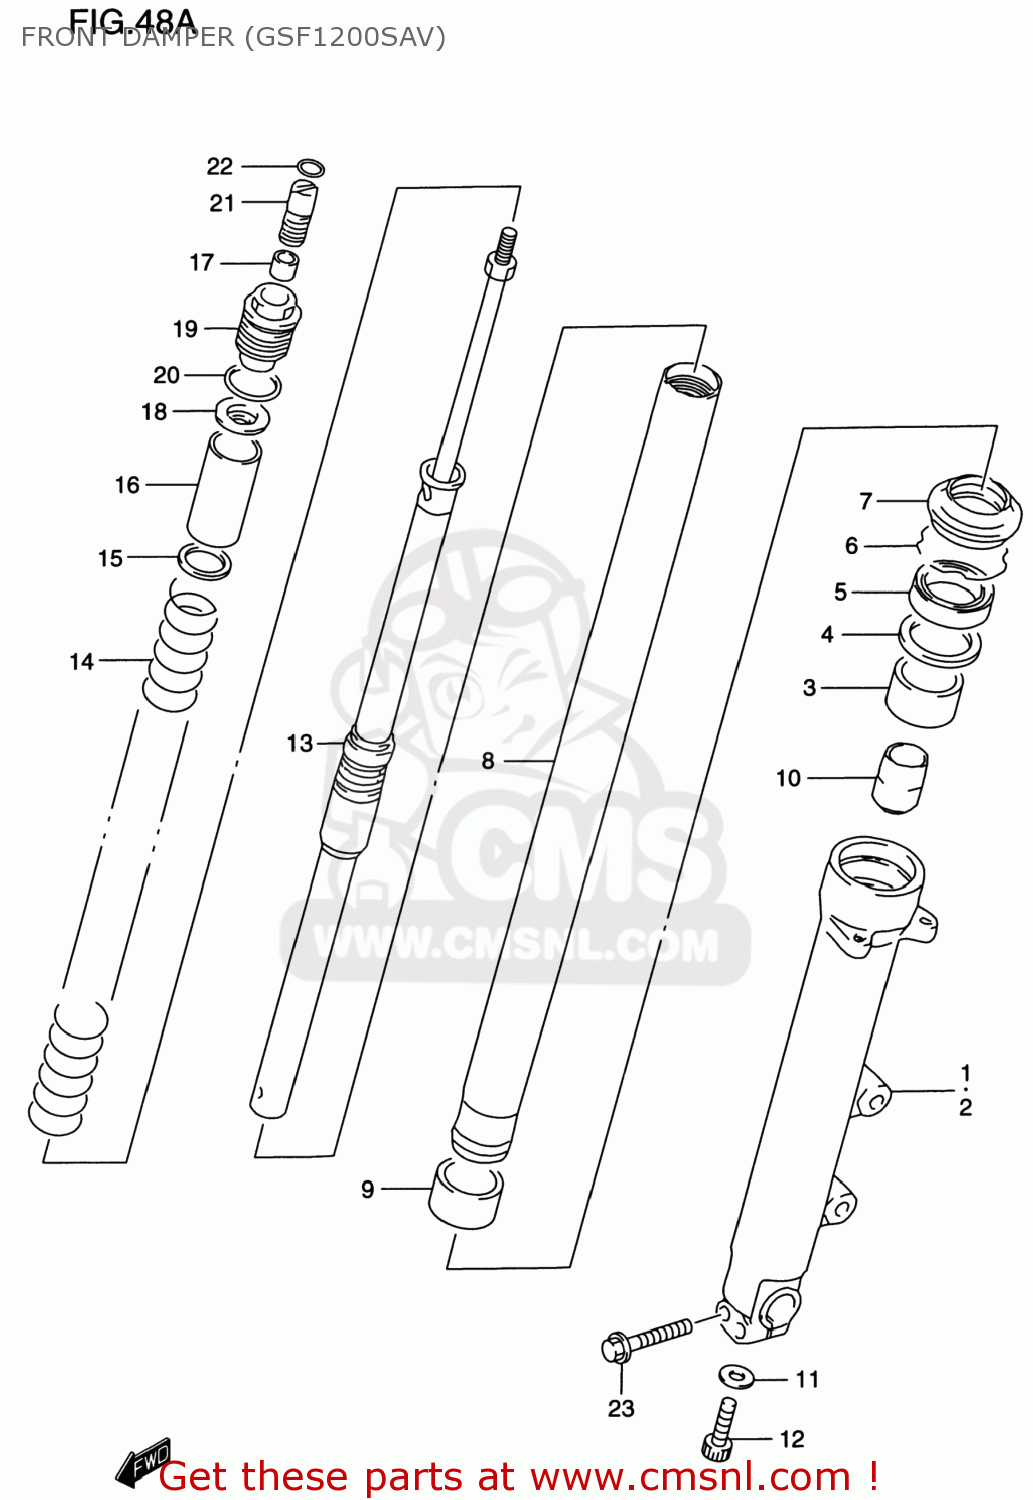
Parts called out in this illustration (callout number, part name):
1	TUBE,OUTER,R
2	TUBE,OUTER,L
3	BUSH,GUIDE
4	SPACER,SEAL
5	SEAL,OIL
6	CIRCLIP,FORK OIL SEAL
7	SEAL,DUST
8	TUBE,INNER
9	BUSH,SLIDE
10	PIECE,OIL LOCK
11	GASKET (NAS)
12	BOLT(8X27)
13	DAMPER,FRONT
14	SPRING,FR
15	SEAT,SPRING LWR
16	COLLAR,SPRING(35X37X50)
17	NUT
18	SEAT,SPRING UPR
19	BOLT,FORK
20	O RING
21	ADJUSTER,SPRING
22	O RING(D:2.5,ID:13.8)
23	BOLT
